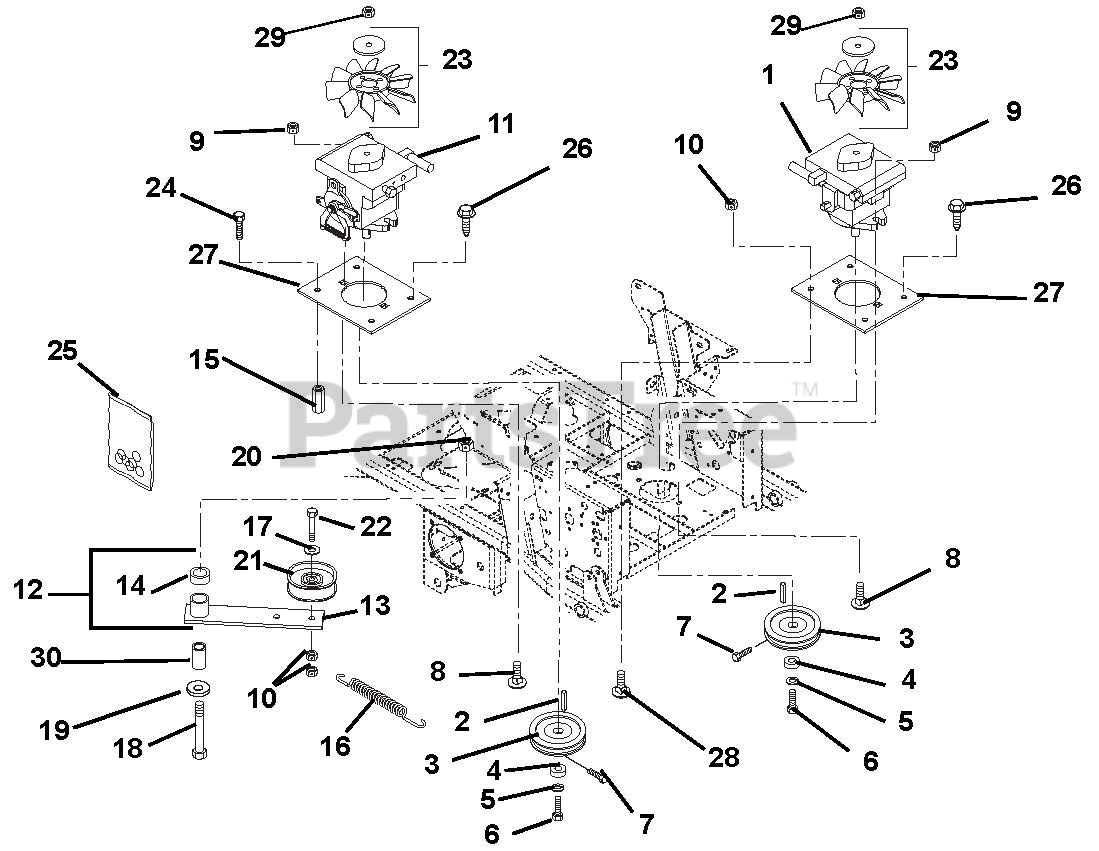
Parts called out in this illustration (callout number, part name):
1	Pump, Hydraulic
2	Key, Square 5 x 5 x 25mm Plain
3	Sheave, Poly-V, 10CC Pump
4	Washer, Flat Steel .281 x 1.0 x .063
5	Washer, Locking .25 x .062
6	Bolt, Hex M6 x 1.0 x 16
7	Screw, Socket Head .25-20 x .50
8	Bolt, Round Head Square Neck .44-14 x 1.50 Grade 5
9	Nut, Nyloc Flange .44-14
10	Nut, Locking-Top-Flange .38-16
11	Pump, Hydraulic, FAN
12	Assembly, Idler Arm Guard Drive
13	Weldment, Idler Arm Ground Drive
14	Bushing, 1.00 x 1.125 x 1.936
15	Nut, Coupling .375-16 x 1.75
16	Spring, Tension .120 x .845 x 6.500
17	Washer, Flat Steel .39 x .75 x.125
18	Bolt, Hex .50-13 x 3.50 Grade 5
19	Washer, Flat Steel .511 x 1.44 x .125
20	Nut, Locking Top Flange .50-13
21	Assembly, 4" Idler, .75 Wide
22	Bolt, Hex .38-16 x 2.25 Grade 5
23	Fan, Cooling
24	Bolt, Hex .38-16 x 1.00 EP30
25	Kit, Pump Seal
26	Screw, Tapping .38-16 x .75 Hex Washer Head Thread Rolling
27	12CC Pump Mounting Plate
28	Bolt, Hex .38-16 x 2.25 Grade 5
29	Nut, Center-Lock .31-24
30	Bushing, Spacer .505/.500 x .999/.996 x 2.05/2.03
